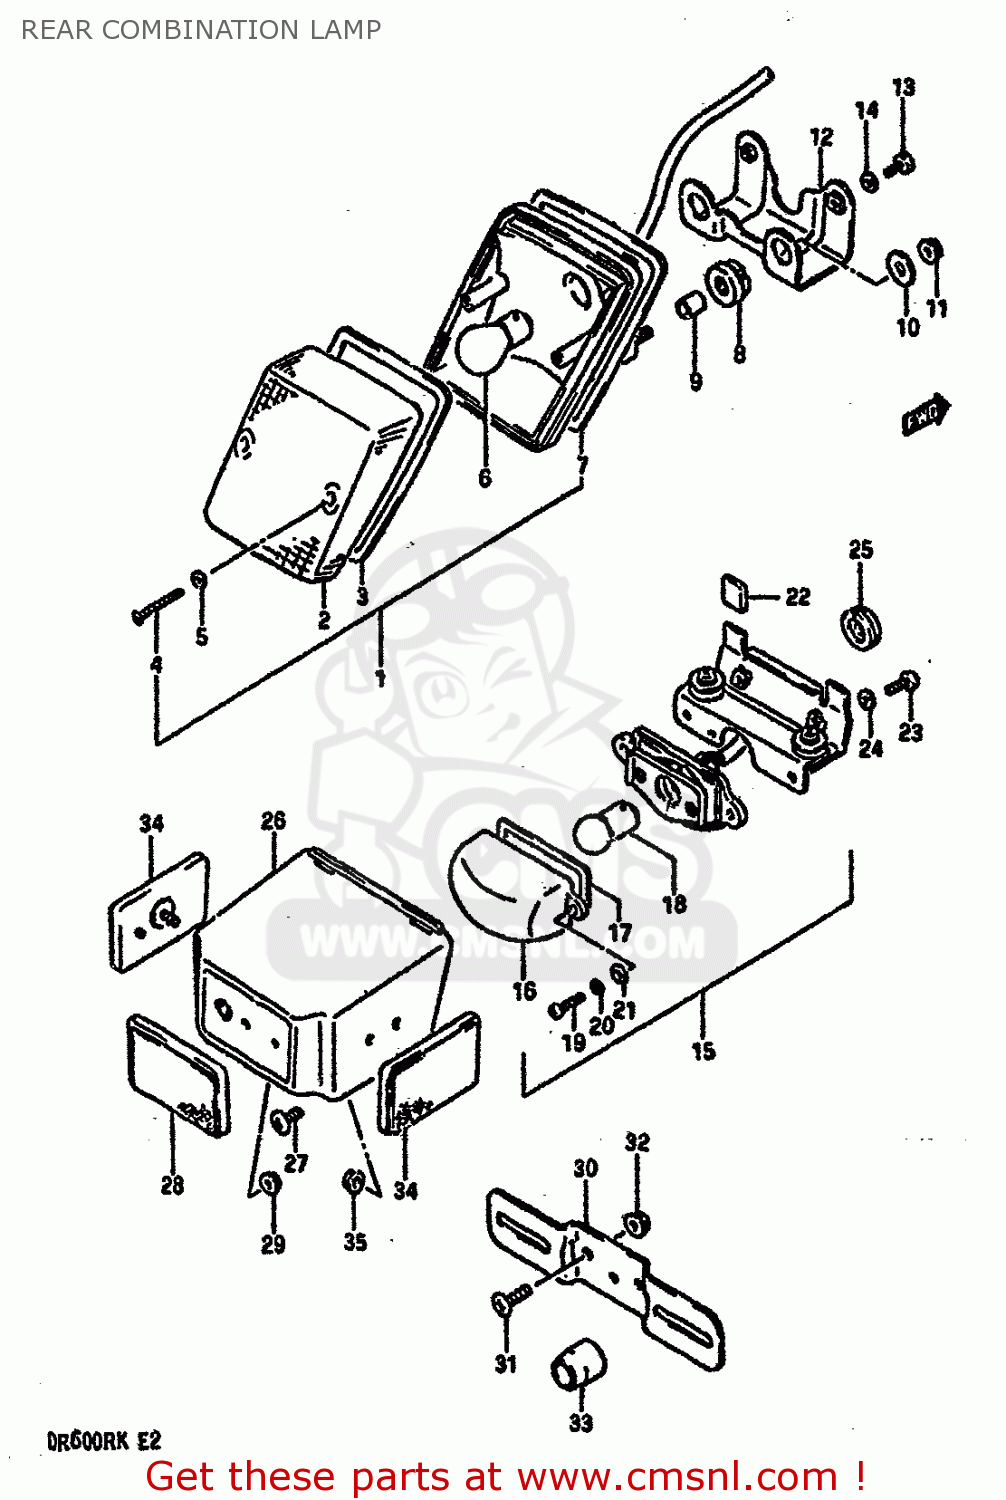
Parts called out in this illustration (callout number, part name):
1	LAMP ASSY,REAR COMBINATION
2	LENS,RR COMBI
3	GASKET,REAR COMBINATION LAMP
4	SCREW TAPP.
5	GASKET (NAS)
6	BULB(12V21/5W)
7	GASKET
8	CUSHION
9	SPACER (6.8X10X10)
10	WASHER (6.5X20X1.2)
11	NUT
12	BRACKET,REAR COMBINATION LAMP
13	BOLT
14	WASHER,LOCK
15	LAMP ASSY, LICENSE
16	LENS,LICENSE LAMP
17	GASKET,LICESE LAMP (NAS)
18	BULB
19	SCREW
20	WASHER,LOCK 4M
21	WASHER 4MM
22	CAP,LICENSE
23	SCREW
24	WASHER,LOCK
25	GROMMET
26	COVER,LICENSE LAMP
27	SCREW
28	RR ASSY,RR
29	NUT
30	BRACKET, LICENSE PLATE
31	SCREW
32	NUT
33	CUSHION
34	REFLEX REFLECTOR, REAR SIDE
35	NUT
